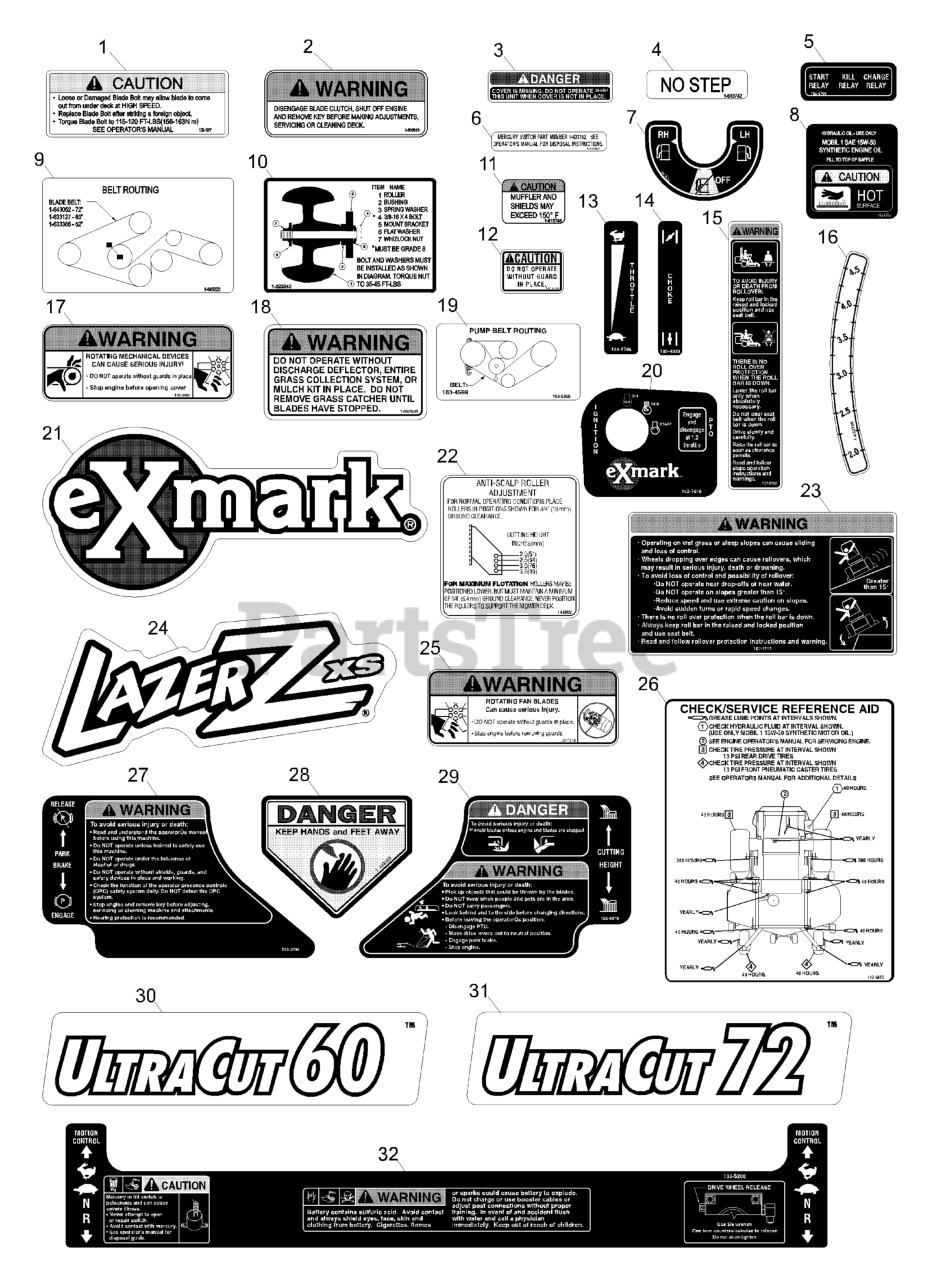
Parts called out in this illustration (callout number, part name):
1	DECAL,BOLT TORQUE
2	DECAL,WARNING
3	DECAL-COVER, MISSING
4	DECAL,NO STEP
5	DECAL,RELAY
6	DECAL-SWITCH, MERCURY
7	DECAL-VALVE, FUEL
9	DECAL,BELT ROUTING
10	DECAL,ROLLER MOUNTING
12	DECAL-GUARD
13	DECAL,THROTTLE ONLY
14	DECAL,CHOKE
15	DECAL-WARNING, FOLDING RO
16	DECAL-HEIGHT, DECK
17	DECAL-DEVICES, ROTATING
18	DECAL-WARNING, DISCHARGE
19	DECAL,PUMP BELT ROUTING
21	DECAL,EXMARK LOGO
22	DECAL,ANTISCALP
23	DECAL-WARNING
24	DECAL,LAZER XS MODEL
25	DECAL,PUMP FAN WARNING
27	DECAL,PARK BRAKE
28	DECAL-DANGER
29	DECAL,CUTTING HEIGHT
30	DECAL,ULTRACUT 60
31	DECAL,ULTRACUT 72
32	DECAL,CONSOLE TOP
